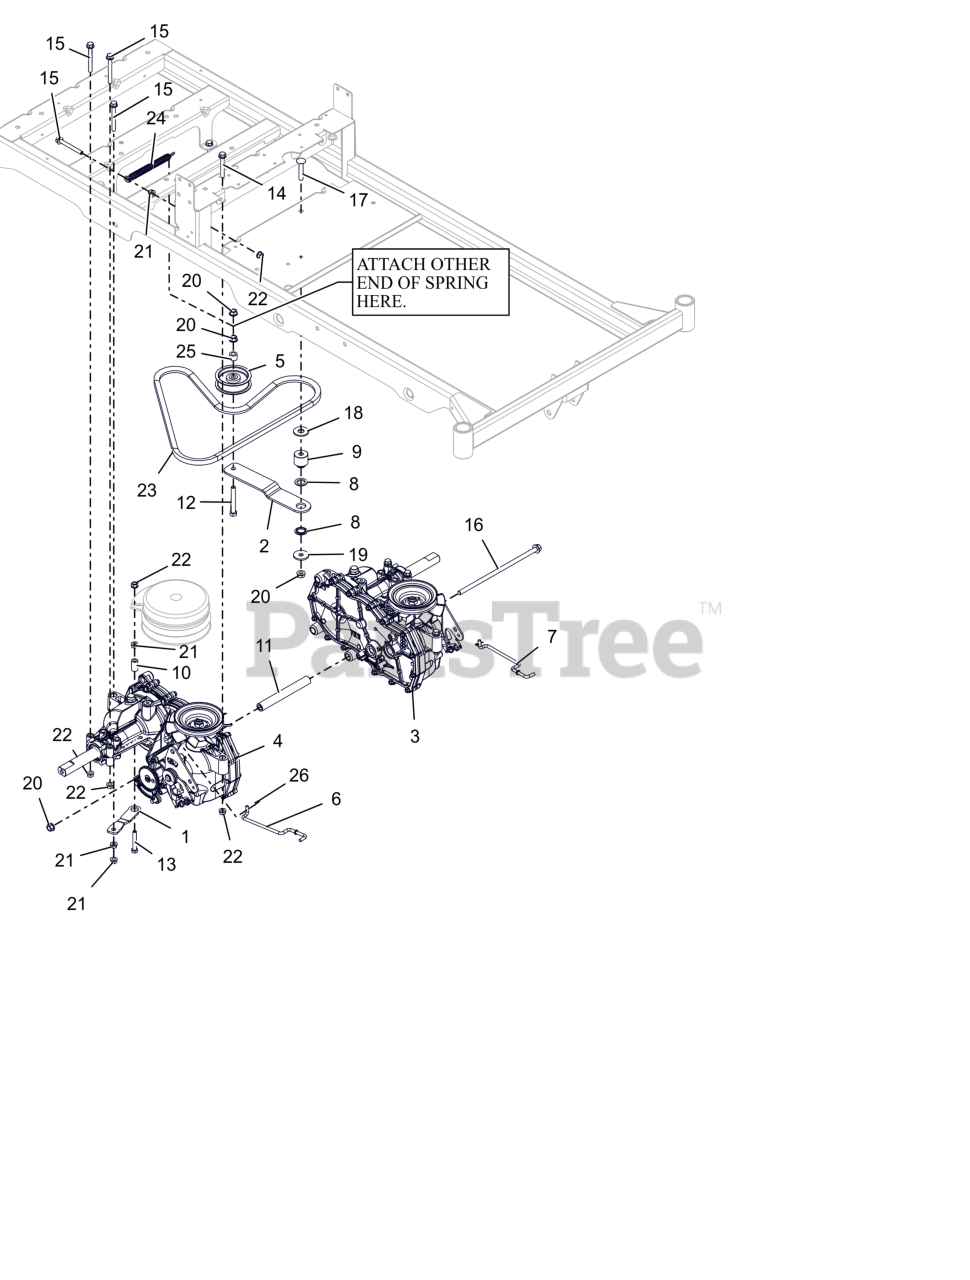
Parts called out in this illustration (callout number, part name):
1	BRKT, CLUTCH
2	IDLER ARM, GROUND DRIVE
3	TRANSAXLE, LH EZT D-SHAFT
4	TRANSAXLE, RH EZT D-SHAFT
5	PULLEY, ENGINE CLUTCH 03608
6	DUMPVALVE, RH LCZ
7	DUMPVALVE, LH LCZ
8	BUSHING, IDLER ARM
9	SPACER, GROUND DRIVE IDLER
10	SPACER, RUBBER 5/16 IDX1.0 LG
11	SPCR, TRANSAXLE .438 ID X .750 OD X 8.18
12	BLT, HEX .38-16X2.75 G5 ZCC
13	BLT, HEX .31-18X2.00 G5 ZCC
14	BLT,HEX-FLG .31-18X2.25 G5 ZCC
15	BLT,HEX-FLG .31-18X2.75 G5 ZCC
16	BLT, HEX-FLG 0.375-16X9.75 GR5 ZC120
17	BLT,RHSSN.375-16X2.00 G5 ZCC
18	WSHR,FLT .563X1.375X.109 ZCC
19	WSHR,FLT .406X1.375X.135 ZCC
20	NUT-LK-CTR-FLG .375-16 GF ZCC
21	NUT,SPNLK-FLG .31-18 G5 ZCC
22	NUT,LK-CTR-FLG .31-18 GF ZCC
23	V-BELT, HA-RAW EDGE
24	SPRING, EXTENSION
25	BSHG-SLV .407X.625X.750 PL
26	PIN, HAIR #178 .06X.77 ZCC
